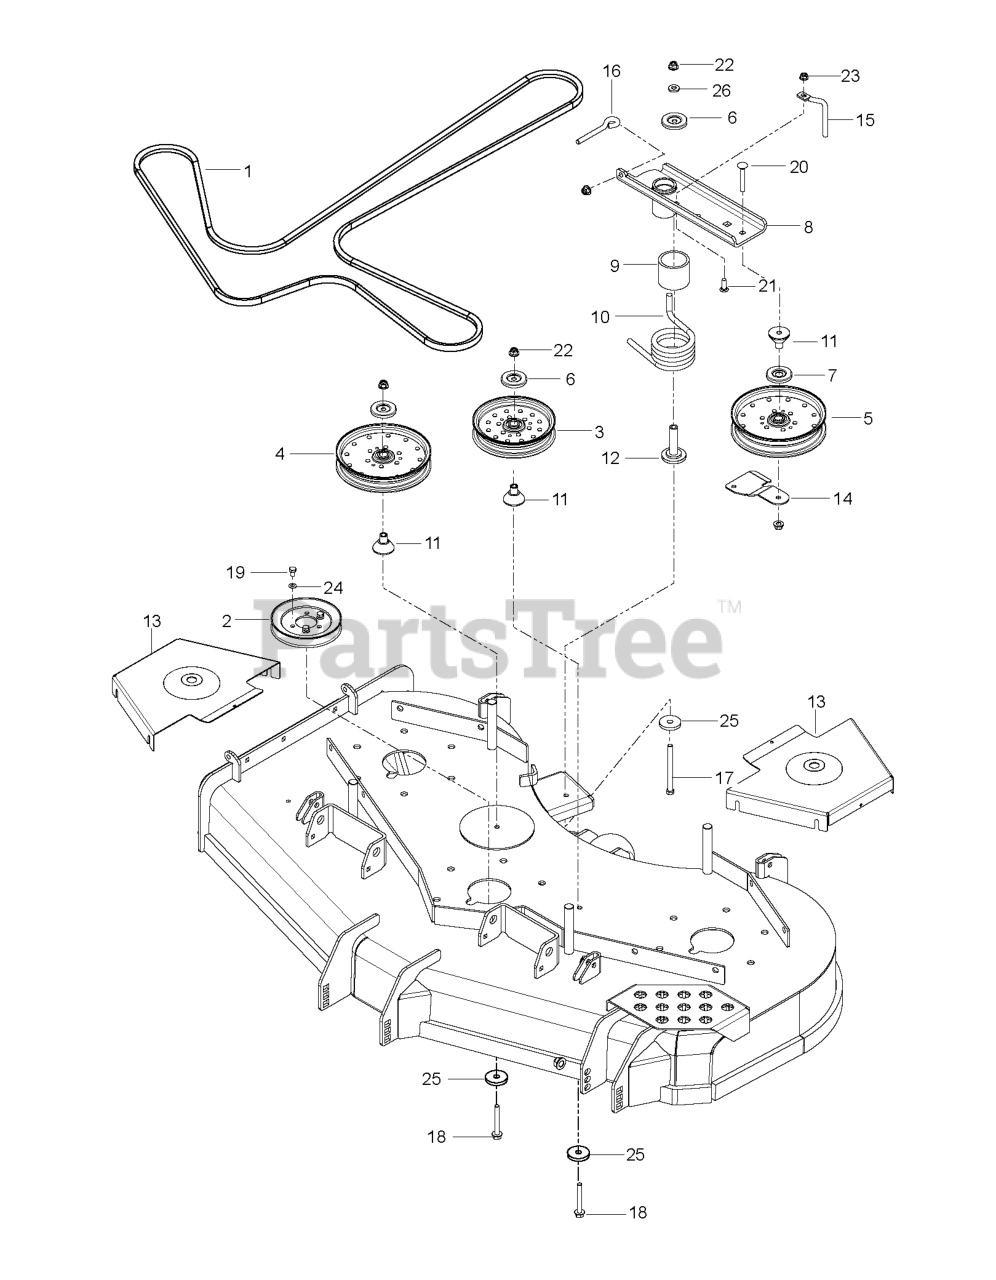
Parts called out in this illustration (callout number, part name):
1	BELT.5V.169.75
2	PULLEY - 5.93 OVER PINS
3	PULLEY - 7" NARROW
4	PULLEY IDLER, 6" NARROW
5	PULLEY - IDLER 7"
6	DUST SHIELD
7	SHIELD, DUST
8	ASSY, IDLER ARM, PZ
9	SPACER, IDLER PIVOT
10	SPRING, TORSION, IDLER
11	BEARING, IDLER ARM
12	BEARING, IDLER PIVOT
13	SHIELD BELT - 60IN SNAPPER RED
14	BELT.GUIDE.BLACK
15	BELT KEEPER
16	EYE BOLT, 3/8 X 4"
17	HCS 3/8-16 X 4-1/2 GR 8 ZD
18	HHFS 3/8-16 X 2-3/4 GR5 ZD
19	HCS 5/16-18 X 1/2 GR 5 ZD
20	CARRIAGE BOLT 3/8-16 X
21	BOLT CRT
22	NUT 3/8-16 HEX FLG NYLOC ZD
23	5/16-18 NYLOC FLANGE NUT
24	WASH 5/16 DISC SPRING ZD
25	SPINDLE WASHER
26	WASHER, 3/8 THICK
